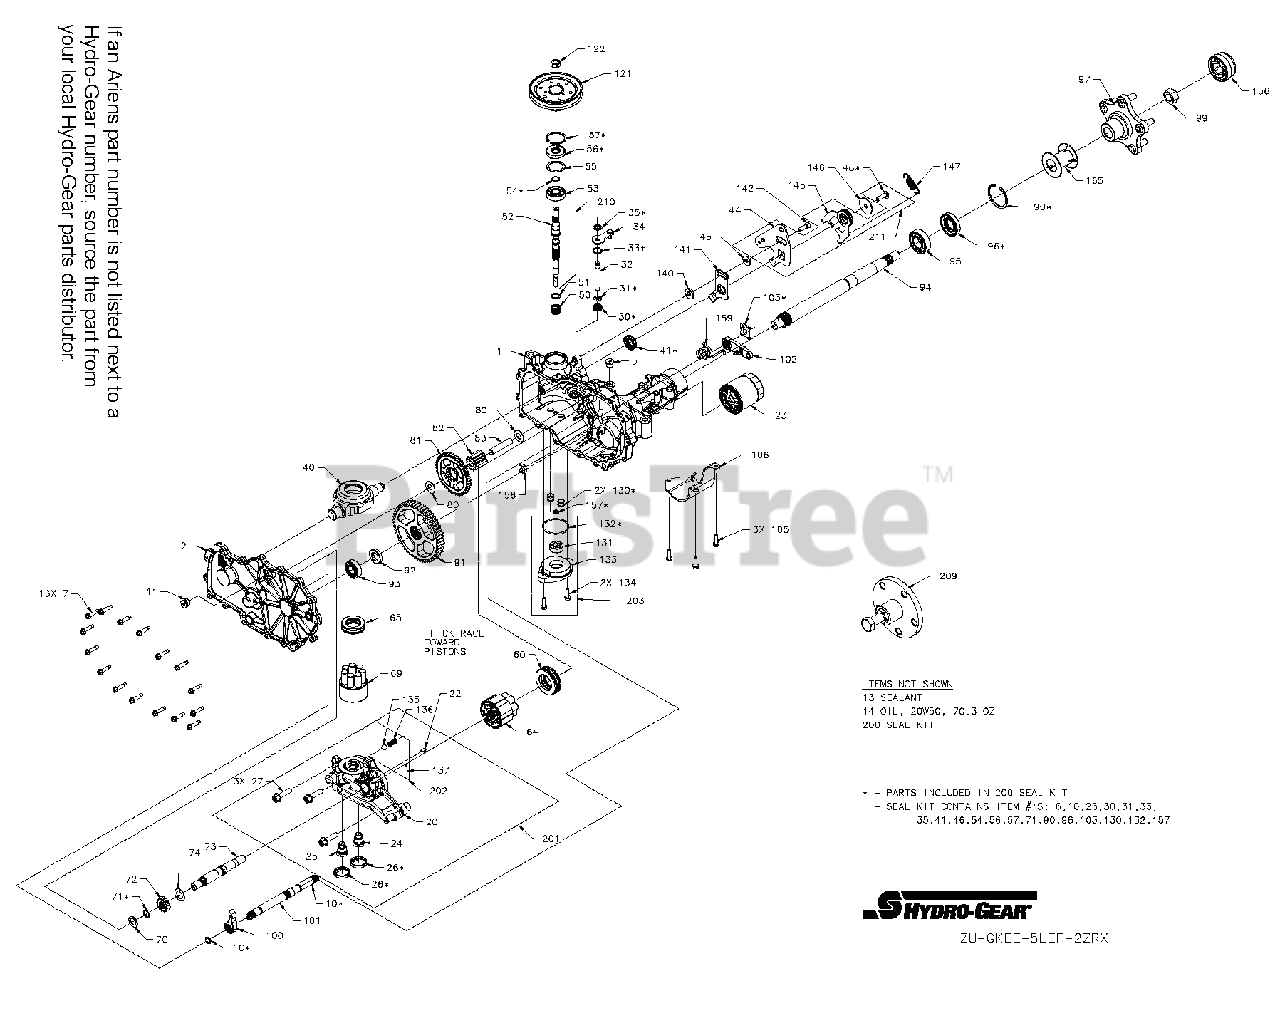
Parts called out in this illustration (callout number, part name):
1	KIT, HOUSING,MAIN,RH,CHRG,CNTL
2	KIT, COVER, SIDE, RH
5	PLUG 9/16-18 (METAL)
11	PLUG 9/16-18 (METAL)
13	SEALANT TUBE 10.1OZ.
20	CENTER SECTION, RH, CHRG
22	PLATE, BYPASS
23	OIL FILTER, TRANSMISSION
24	SHOCK VALVE ASSEMBLY 220 BAR
25	SHOCK VALVE ASSEMBLY 220 BAR
27	HFHCS 3/8-16X1.5 (PATCH)
30	SEAL, LIP .375X.75X.25
31	RING. RETAINING
32	ROD, BYPASS
33	RING, RET .750 INTRNL
34	ARM, BYPASS
35	RING, RTNG .
40	TRUNNION, SWASHPLATE
41	SEAL, LIP 18X32X7
44	ARM, CONTROL, RH
46	TWHCS 5/16-24 X 1.00
50	SPRING, BLOCK
51	WASHER. THRUST .59 X .79 X .04
52	SHAFT, INPUT
54	RING, RET WIRE .561 ID
55	WASHER 1.23X1.56X.04
56	SEAL, LIP 17X40X7
57	RING, RET 1.56 INT
60	BEARING, THRUST
65	BRG, THRUST PLASTIC CAGE
69	ASS'Y, BLOCK 7 PISTON
72	GEAR, 13T, STEEL
73	SHAFT, MOTOR
80	WASHER .5X1.0X.032
82	GEAR, 11T, STEEL
83	JACK SHAFT (PIN)
90	RING, RET 2.06 INT
94	SHAFT, AXLE
95	BEARING, BALL 25.4 X 52 X 15
96	SEAL, LIP
97	KIT, HUB, 5 BOLT
99	NUT, HEX, LOCK 3/4-16
100	PAWL, BRAKE
101	SHAFT, BRAKE
102	KIT, HANDLE, ACTUATING
103	CLIP, RETAINING
106	GUARD, FILTER, RH
122	NUT, HEX 1/2-20 PATCH
130	TUBE, CONNECTING
131	GEROTOR ASSEMBLY (1.9 cc/rev)
132	O-RING HYDROGEAR 52250
133	COVER, CHARGE PUMP
136	SPRING, RELIEF
141	ARM, NEUTRAL RIGHT
142	SHCS 5/16-24X1 PATCH
145	ASSEMBLY, RTN, CW
146	WASHER
147	SPRING, HYDROGEAR P/N 51833
157	SEAL, LIP 8 X 12 X 3 VC
158	MAGNET, RING
159	SPRING, TORSION CCW
200	KIT, SEAL
201	KIT, CENTER SECTION, RH, CHRG
202	KIT, CHARGE RELIEF
203	KIT, CHARGE PUMP
209	HUB PULLER, 5 BOLT
210	KIT, INPUT SHAFT
211	KIT, RTN, CW
